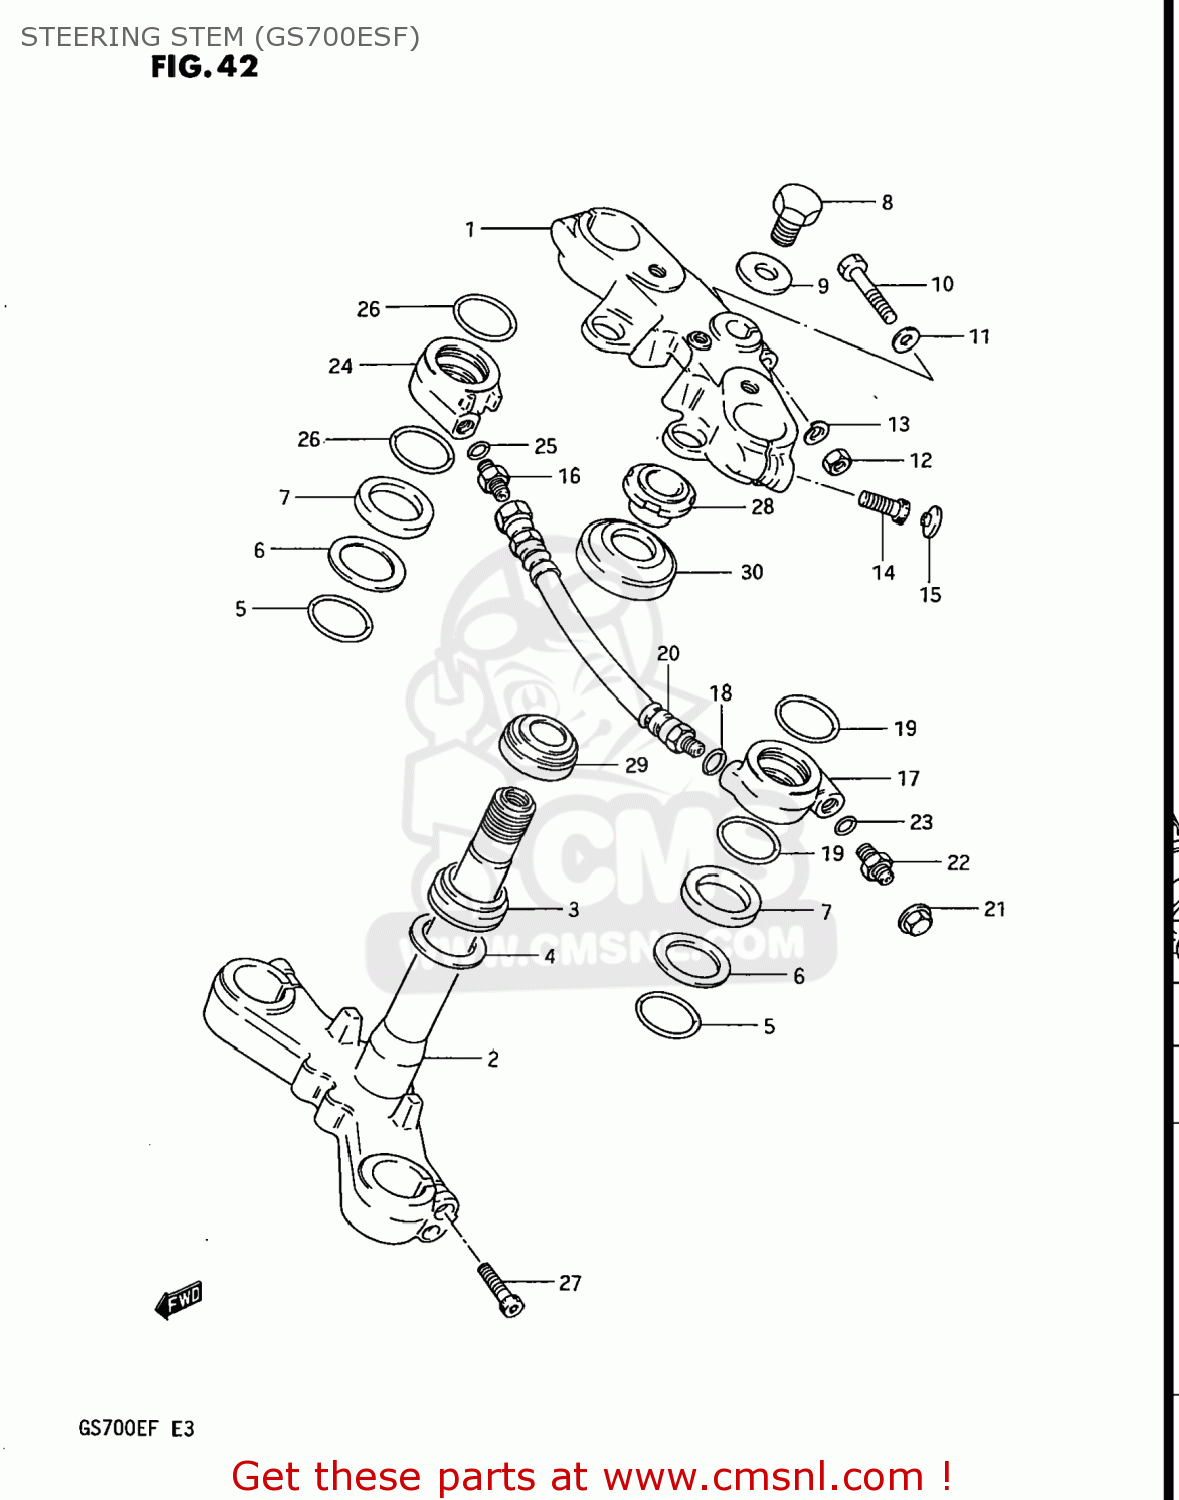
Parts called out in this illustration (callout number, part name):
1	HEAD,STEERING STEM
2	STEM,STEERING
3	BEARING
4	WASHER,THRUST
5	RING,STOPPER
6	WASHER
7	CUSHION
8	BOLT
9	WASHER,STEM HEAD
10	BOLT
11	WASHER
12	NUT 8MM
13	WASHER,LOCK,8.
14	NUT,STEM HEAD
15	CAP(OD:20)
16	CONNECTOR
17	JOINT,AIR,LEFT
18	O-RING (D:3.8 ID:19)
19	O RING
20	TUBE,JOINT
21	CAP,FRONT FORK AIR VALVE
22	VALVE,AIR
23	O-RING (D:3.8 ID:19)
24	JOINT,AIR,RIGHT
25	O-RING (D:3.8 ID:19)
26	O RING
27	BOLT 8X35
28	NUT,STEERING STEM
29	TAPER,ROLLER BEARING
30	DUST SEAL,STEERING UPR
